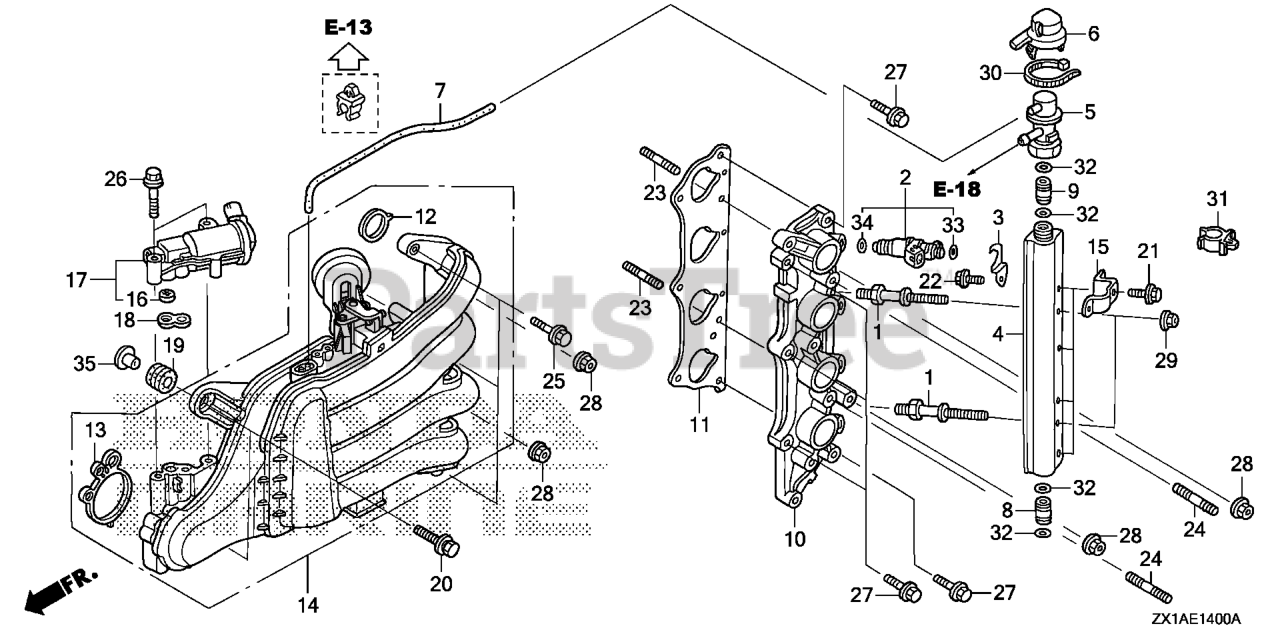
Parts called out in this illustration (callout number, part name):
1	BOLT, FUEL PIPE
2	INJECTOR ASSY., FUEL
3	CLIP, INJECTOR
4	LINE, FUEL
5	REGULATOR ASSY., PRESSURE
6	CAP, REGULATOR
7	TUBE, PRESSURE REGULATOR CONTROL
8	JOINT, FUEL PIPE
9	JOINT, FUEL PIPE
10	BASE, INJECTOR *NH8* (DARK GRAY)
11	GASKET A, INJECTOR BASE
12	GASKET, IN. MANIFOLD
13	GASKET, THROTTLE BODY
14	MANIFOLD, INLET
15	BRACKET A, HARNESS CLIP
16	FILTER, ELECTRONIC AIR CONTROL VALVE (TOYO ROKI)
17	VALVE ASSY., ELECTRONIC AIR CONTROL
18	GASKET, ELECTRONIC AIR CONTROL VALVE
19	RUBBER, FR. CARRIER CUSHION
20	BOLT-WASHER (8X35)
21	BOLT, FLANGE (6X14)
22	BOLT, FLANGE (6X10)
22	BOLT (6X10)
23	BOLT 2, STUD (8X25)
24	BOLT, STUD (8X32)
25	BOLT, FLANGE (8X35)
26	BOLT, FLANGE (8X45)
27	BOLT, FLANGE (8X25)
28	NUT, FLANGE (8MM)
29	NUT, FLANGE (6MM)
30	BAND, HARNESS
31	CLIP, FUEL TUBE (14) (NOT AVAILABLE)
32	O-RING (7.8X1.9) (ARAI)
33	O-RING (7.47X3.6)
34	O-RING (7.45X3.61) (NOK)
35	COLLAR (8.5X14.5)
